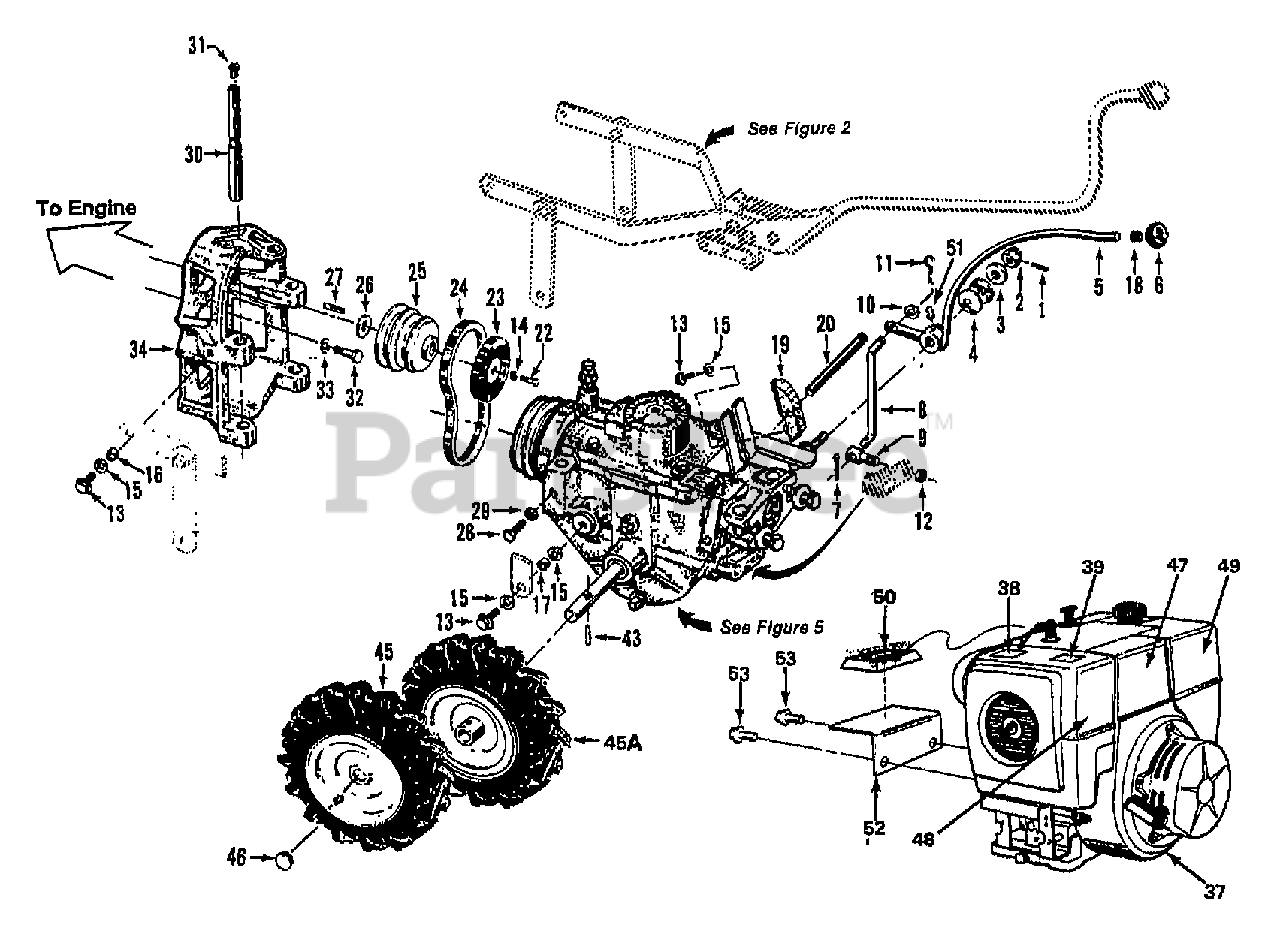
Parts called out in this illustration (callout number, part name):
1	PIN-SPRING .125 X 1
2	NUT-HEX 1/2-20
3	WASHER-# SHOULDER ZP (SHOULDER FACES DISC WASHERS)
4	WASHER-# 1.97X1X.118 (CONCAVE SURFACES FACE EACH OTHER)
5	LVR-W/KNOB WHEEL SPEED (INCL. #6 & #18)
6	KNOB-WHEEL SPEED HORSE (INCL. #18 & PLASTIC DECAL INLAY)
7	PIN-COTTER .094X1.0
8	ROD-CONNECTING
9	SWIVEL
10	WASHER-FLAT 5/16 SAE
11	PIN-CLIP .08
12	NUT-H/LK 5/16-18
13	SCR-HFLK 3/8-16X1.00 ZP
14	WASHER-LK .375 @ DEPL
15	WASHER-FLAT 3/8 SAE
16	BUSHING-.5X.375X.325
17	BUSHING-.5X.375X.3
18	RING-TOLERANCE .5325 ID
19	KIT-ADJ BLOCK 4 SP (INCL. # 13,15,& 20)
20	BAR-ADJUST
21	THIS REF. NOT USED.
22	SCR-HH 3/8-24X1.5 G5
23	KIT-ADJ BLOCK/REV DISC (INCL. #19)
23	DISC-REV
24	BELT-V
25	PULLEY-ENG MACH (POWER TAKE OFF)
26	SHIM-1.0X.7656X.062
26	SHIM-1.0X.7656X.031
27	KEY-.188 SQ X 2.33
28	SCR-HH 5/16-18X1.0 G5 ZP
29	NUT-HEX 5/16-18 ZP
30	PIN-MOTOR MOUNT STAINLESS
31	PLUG-CAP (RED)
32	BOLT-HH 5/16-24X1.125 G5 ZP
33	WASHER-LK .312 ZP
34	MOTOR MOUNT-BLACK
35	THIS REF. NOT USED.
36	THIS REF. NOT USED.
37	8HP KOHLER ENGINE ELEC START MOD # M8ST
38	DECAL-HOT SURFACE
39	DECAL-STABIL STARTING
40	THIS REF. NOT USED.
41	THIS REF. NOT USED.
42	THIS REF. NOT USED.
43	PIN-SPIROL .313 X 1.5
44	THIS REF. NOT USED.
45	ASSM-TIRE&WHEEL LH SVR
45A	ASSM-TIRE&WHEEL RH SVR
46	CAP-HUB BLK PLASTIC
47	DECAL-LOGO KOH MAGNUM
48	DECAL-ACCENT MAG AIR CLNR
49	DECAL-ACCENT MAG FUEL TNK
50	KIT-HOUR METER
51	FITTING-GREASE STREIGHT
52	BRKT-HOUR METER BLACK
